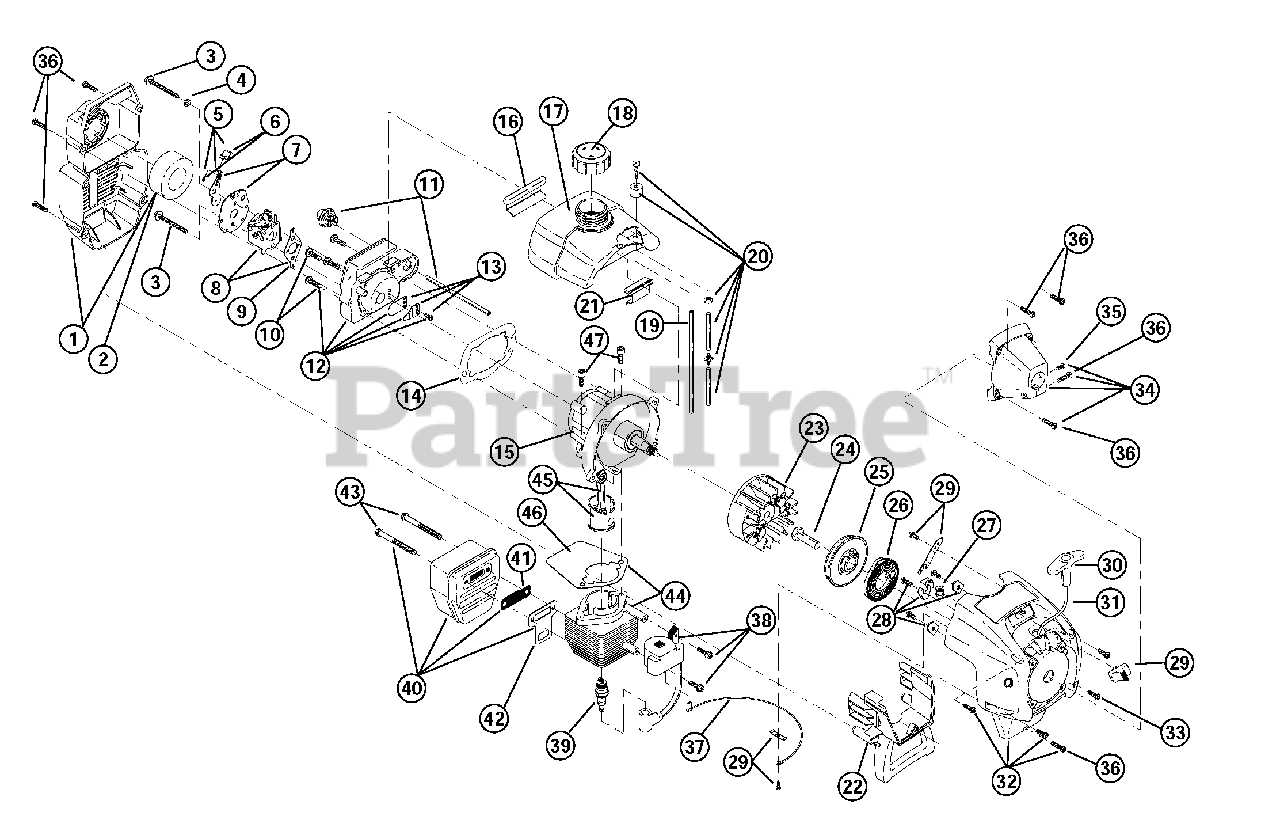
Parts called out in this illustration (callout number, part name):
1	Air Cleaner/Muffler Cover Assembly
2	Air Cleaner Filter
3	Carburetor Mounting Screw Assembly
4	Wavey Washer
5	Choke Lever Assembly
6	Choke Knob and Screw
7	Choke Lever and Plate
8	Carburetor Assembly
9	Carburetor Gasket
10	Carb Mount Screw
11	Primer and Hose Assembly
12	Carb Mount Assembly
13	Reed Assembly
14	Carburetor Mount Gasket
15	Crank Case Service Assembly
16	Rear Mounting Pad
17	Fuel Tank Assembly
18	Fuel Cap Assembly
19	Fuel Return Line
20	Fuel Line Assembly
21	Front Mounting Pad
22	Shroud Extension and Stand
23	Flywheel Assembly
25	Recoil Pulley Assembly
26	Recoil Spring
27	Rope Guide
28	Pulley Retainer Assembly
29	Switch Assembly
30	Pull Handle
32	Starter Housing Assembly
33	Housing Screw
34	Clutch Cover Assembly
35	Anti-Rotation Screw
36	Clamping Screw
37	Wire Lead
38	Module Assembly
39	Spark Plug
40	Muffler Assembly
41	Spark Arrestor Screen
42	Exhaust Gasket
43	Muffler Mounting Bolt Assembly
44	Cylinder Assembly
45	Piston and Rod Assembly
46	Cylinder Gasket
47	Cylinder Bolt
